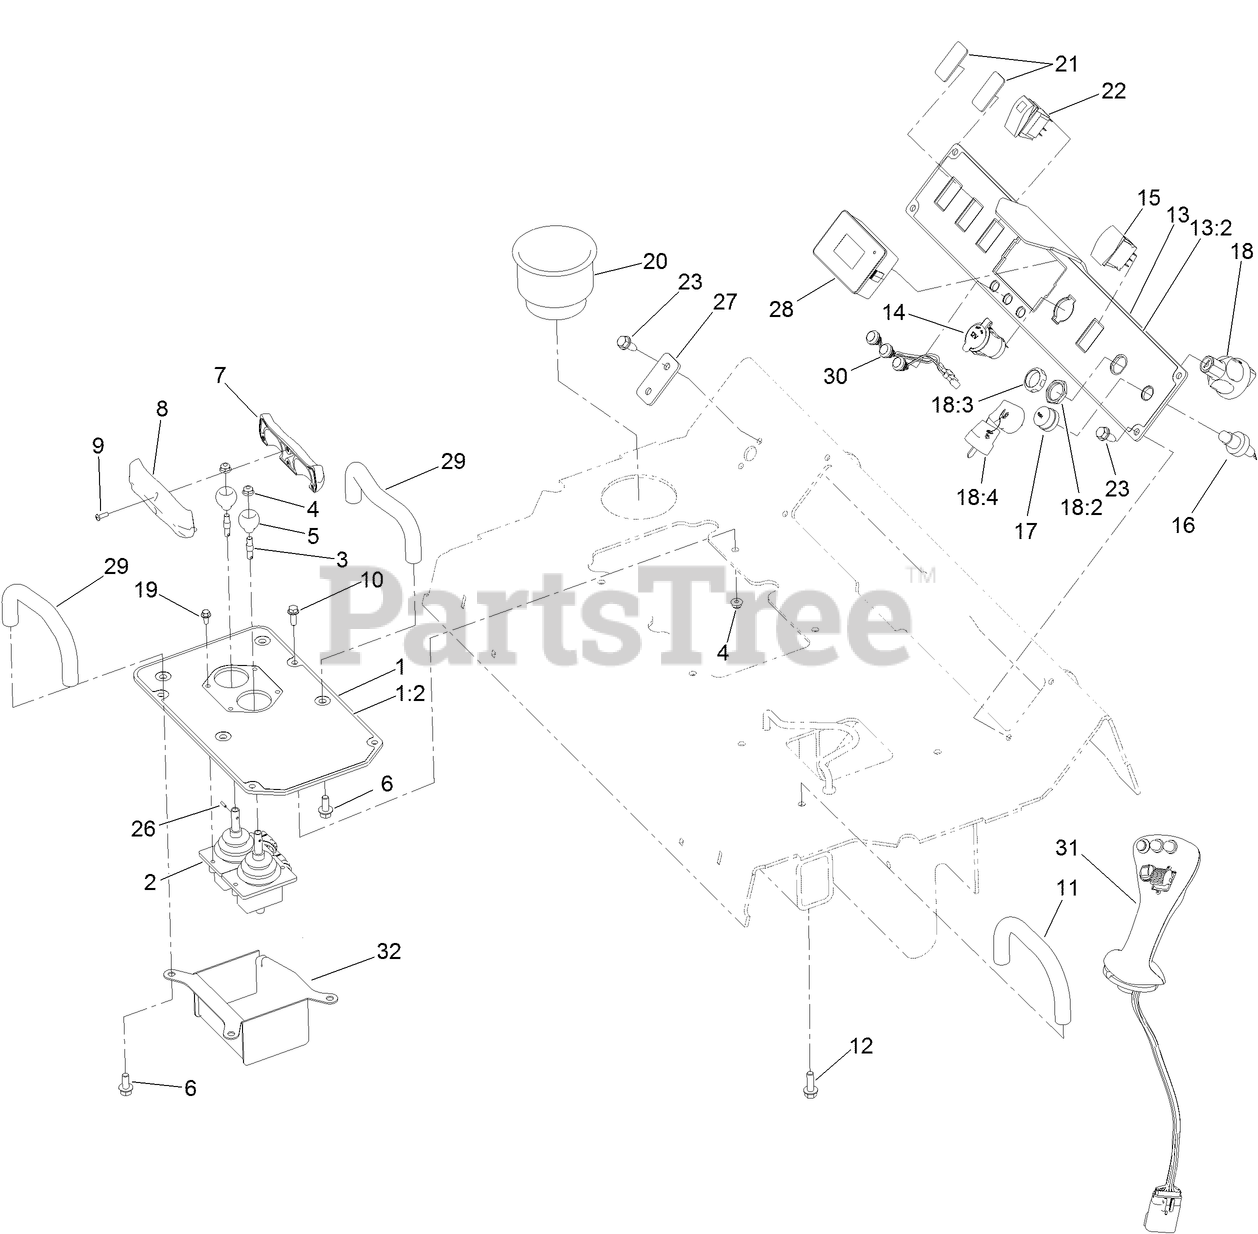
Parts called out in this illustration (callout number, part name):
1	PLATE-CONTROLS, TRACTION
1:2	DECAL-TRACTION
2	LEVER-CONTROL
3	SHAFT-HANDLE
4	NUT-HF
5	BALL-TRACTION
6	SCREW-HHF
7	HANDLE-FRONT
8	HANDLE-REAR
9	SCREW
10	SCREW-HHF
11	BAR-REFERENCE
12	SCREW-HHF
13	PLATE-CONTROL, MAIN
13:2	DECAL-CONTROLS
14	PORT-POWER, 12V
15	SWITCH
16	SWITCH-HORN
17	NUT-WEATHERPROOF
18	IGNITION SWITCH ASM
18:2	NUT-HEX
18:3	NUT-FACE
18:4	SET-KEY, IGNITION
19	SCREW-HFH
20	CUP-HOLDER
21	PLUG-HOLE
22	SWITCH
23	SCREW-HWH
26	PIN-ROLL
27	PLATE-BLANK
28	TDM 2002
29	BAR-REFERENCE
30	SWITCH-PUSHBUTTON
31	HANDLE-JOYSTICK
32	COVER-VALVE
